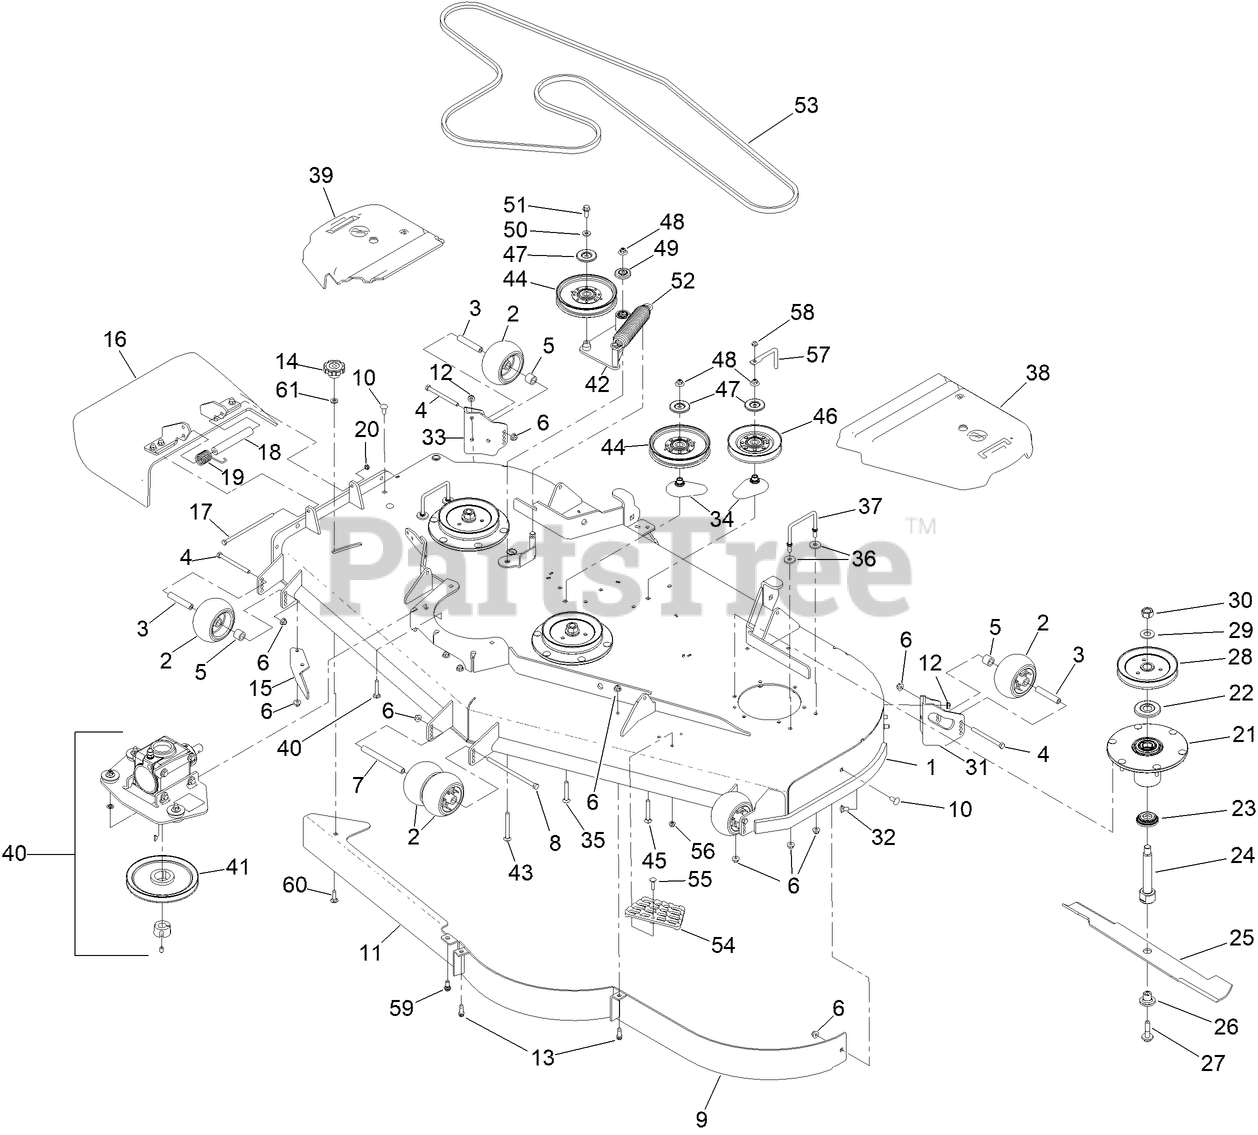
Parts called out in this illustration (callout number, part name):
1	DECK DECAL ASM
2	ROLLER-SCALP, ANTI
3	TUBE-SPANNER
4	SCREW-HH
5	TUBE-SPACER
6	NUT-HF, NI
7	SPACER-WHEEL
8	SCREW-HH
10	SCREW-CARR
11	PLATE-BAFFLE
12	NUT-HHF, WHIZ
15	BAFFLE-DISCHARGE
16	RUBBER DEFLECTOR ASM
17	SCREW-HH
18	SPACER
19	SPRING-TORSION
20	NUT-LOCK, NI
21	SPINDLE ASM
22	GUARD-BEARING, TOP
23	GUARD-BOTTOM
24	SHAFT-SPINDLE
26	BUSHING-HEX
27	SCREW-SEMS
28	SHEAVE-BLADE DRIVE 6.50
29	WASHER
30	NUT-HEX
31	MOUNT-WHEEL, LH
32	SCREW-CARR
33	MOUNT-WHEEL, RH
34	SPACER-PULLEY
35	SCREW-CARR
36	WASHER
37	WIREFORM-COVER
38	COVER-BELT, LH
39	SHIELD-BELT
40	GEARBOX ASM
41	PULLEY
42	IDLER ARM ASM
43	BOLT-SHOULDER, CARRIAGE
44	IDLER-PULLEY
45	SCREW-CARR
46	IDLER V
47	SHIELD-DUST
48	NUT-FLANGE, NI
49	GUARD-TOP
50	SPACER
51	SCREW-HHF
52	SPRING-EXTENSION
53	BELT-V
54	STEP-DECK
55	SCREW-CARR
56	NUT-HF, NI
57	GUIDE-BELT
59	BOLT-SHOULDER
60	BOLT-CARR
61	WASHER-HARDENED
